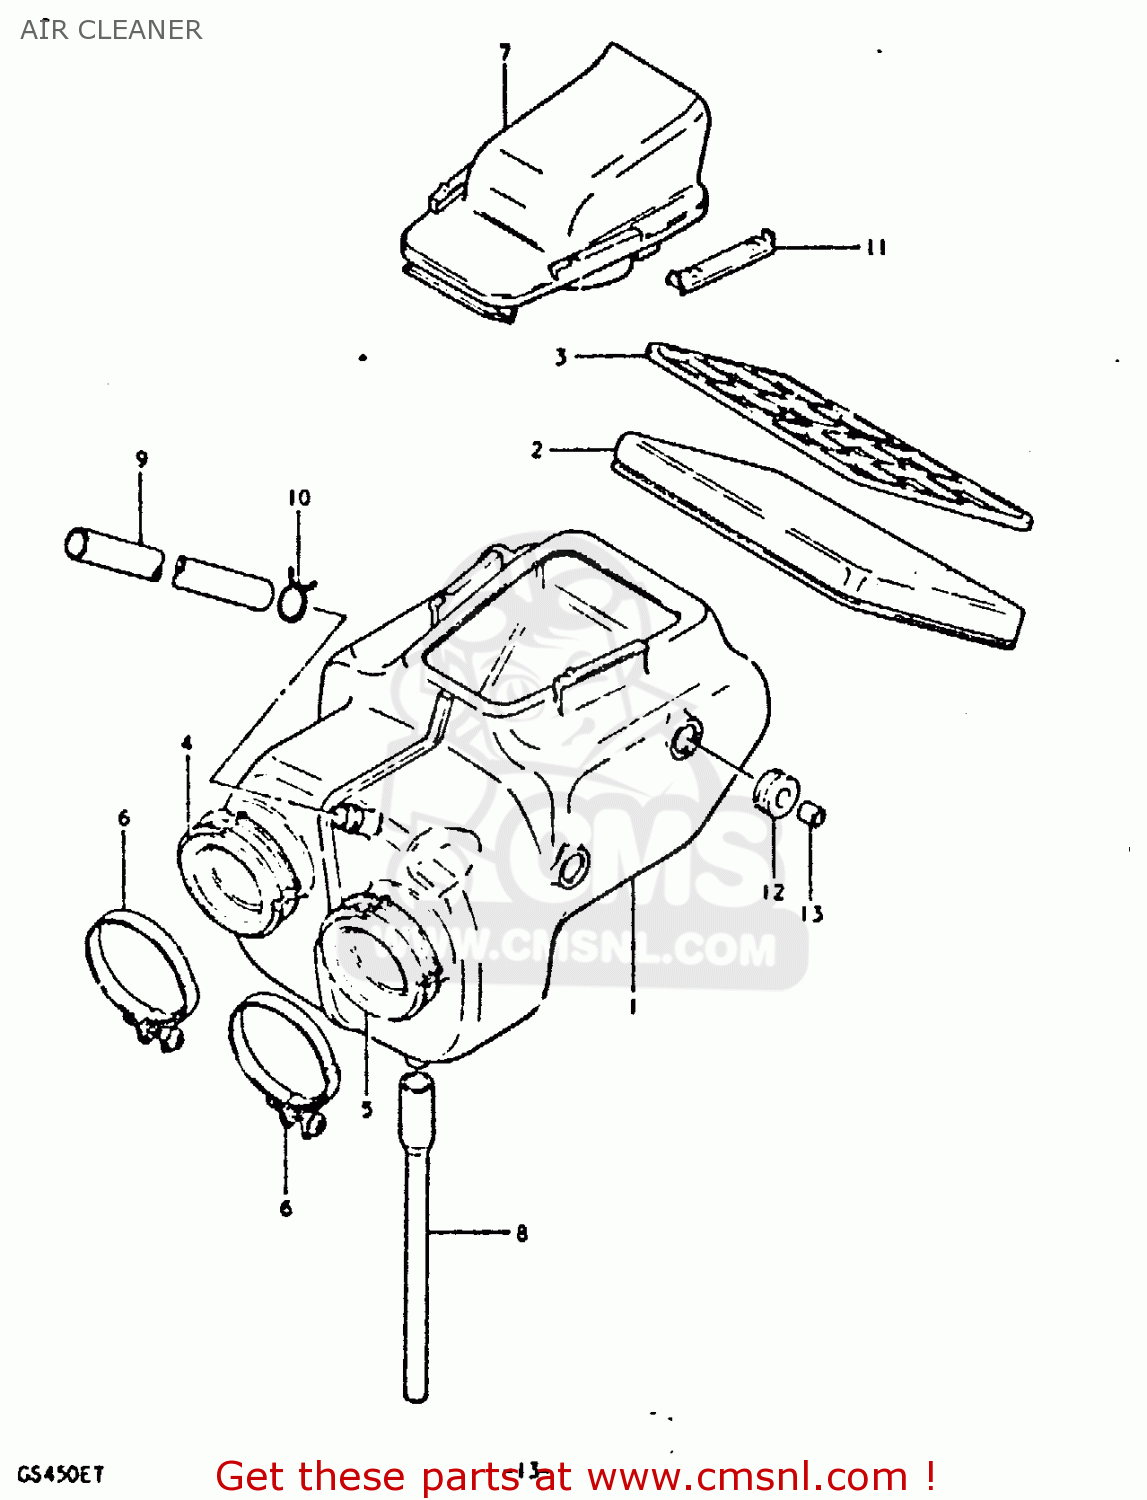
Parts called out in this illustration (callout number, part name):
1	CLEANER ASSEMBLY,AIR
2	FILTER
3	HOLDER NO.2
4	OUTLET,R
5	OUTLET,L
6	CLAMP
7	CAP
8	DRAIN TUBE
9	TUBE,BREATHER
10	CLAMP
11	SLIDER
12	CUSHION
13	SPACER(6.1X9X7.5)
